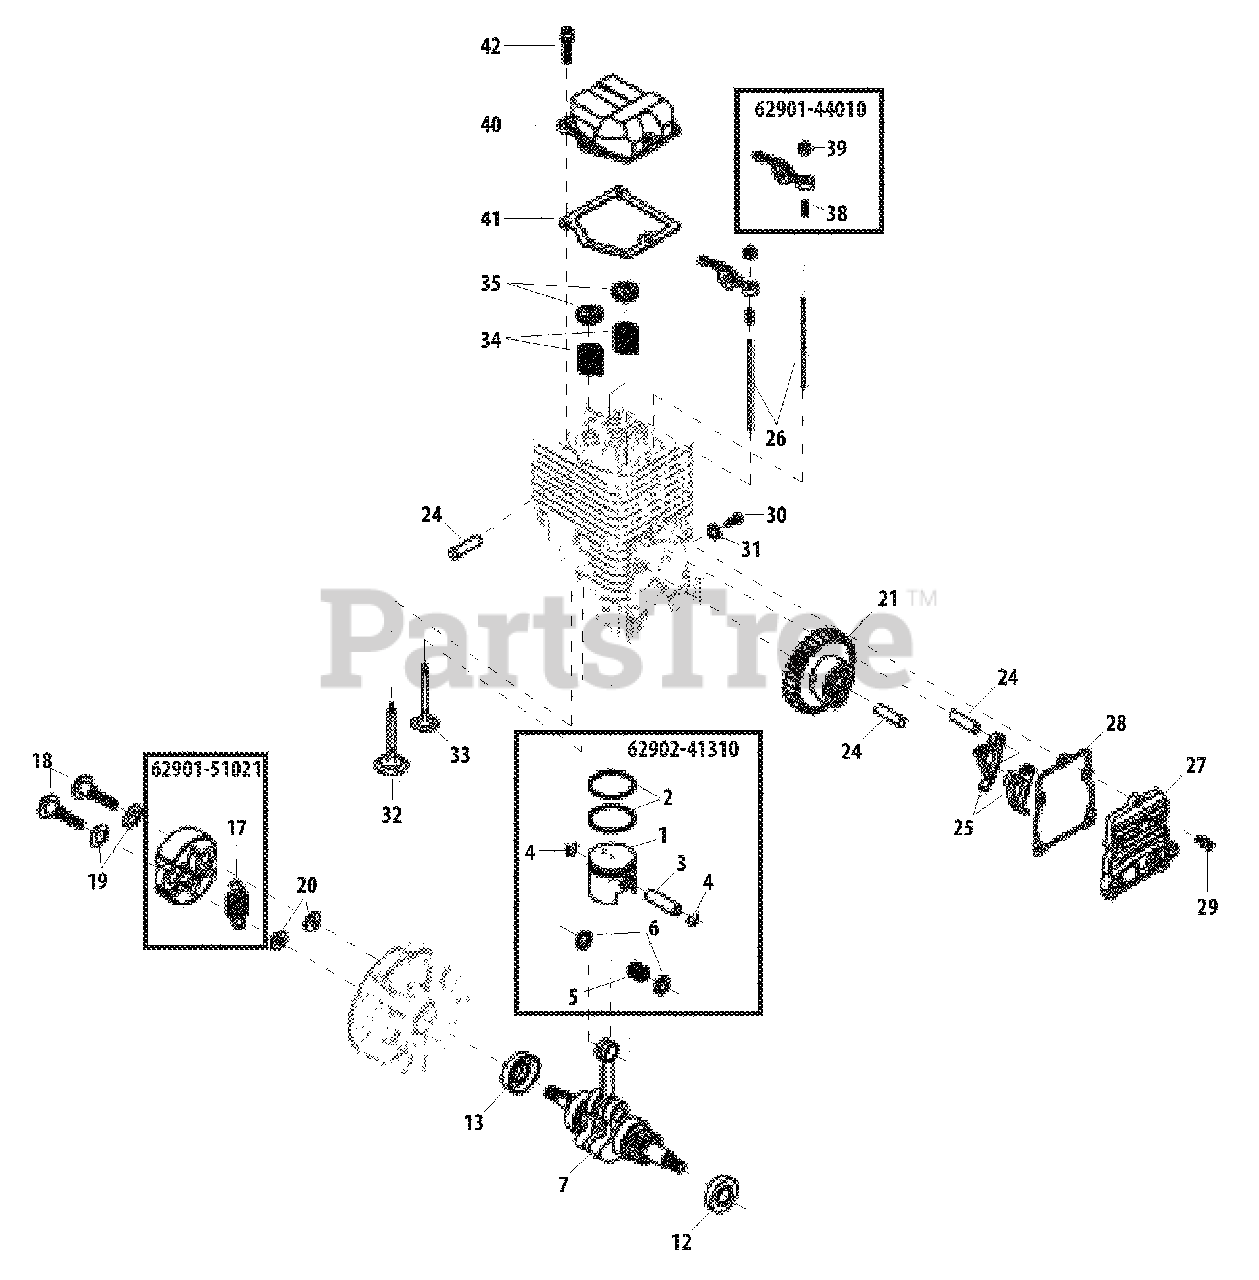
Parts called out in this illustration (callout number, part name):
1	PISTON
2	RING, PISTON
3	PIN, PISTON
4	RING, SNAP
5	BEARING, NEEDLE 9
6	WASHER, THRUST 9
7	CRANKSHAFT ASSY
12	SEAL, OIL 12
13	SEAL, OIL 12
17	SPRING, CLUTCH
18	BOLT, CLUTCH
19	WASHER, SPRING
20	WASHER 6 MM
21	GEAR, CAM
24	PIN, LOCATING Ø5×29.8 MM
25	FOLLOWER, CAM
26	PUSHROD
27	COVER, CAM GEAR
28	GASKET, CAM GEAR
29	BOLT M4×14
30	SCREW M5
31	WASHER Ø10ר5.5×2
32	VALVE, INTAKE
33	VALVE, EXHAUST
34	SPRING, VALVE
35	VALVE RETAINER ASSY
38	SCREW, ADJUSTER
39	LOCKNUT, ADJUSTER
40	COVER, ROCKER ARM
41	GASKET, ROCKER ARM
42	BOLT M4×14
62901-44010	ROCKER ARM ASSY
62901-51021	SHOE ASSY, CLUTCH
62902-41310	PISTON KIT
